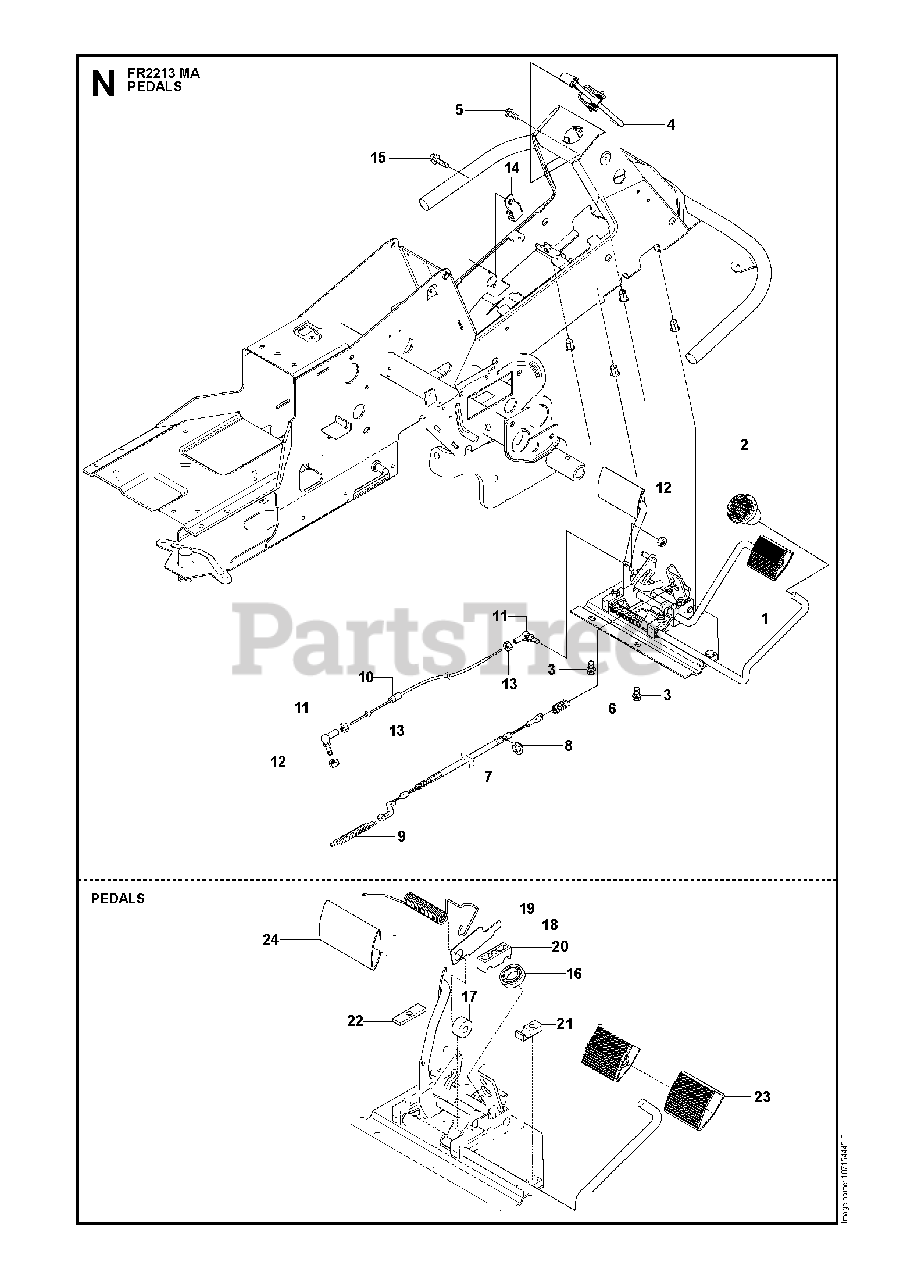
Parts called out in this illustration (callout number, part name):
1	PEDAL ASSEMBLY
2	KNOB
4	BRAKE LEVER ASSY
7	BRAKE WIRE
10	%WIRE
11	CONNECTOR
12	LOCKNUT M5
16	BALL BEARING 6002-2RS1
17	ROLLER
18	PLATE
19	SPRING
20	PEDAL SHAFT CLAMP
21	SUPPORT
22	PLATE
23	PEDAL RUBBER
24	PEDAL RUBBER, SF
